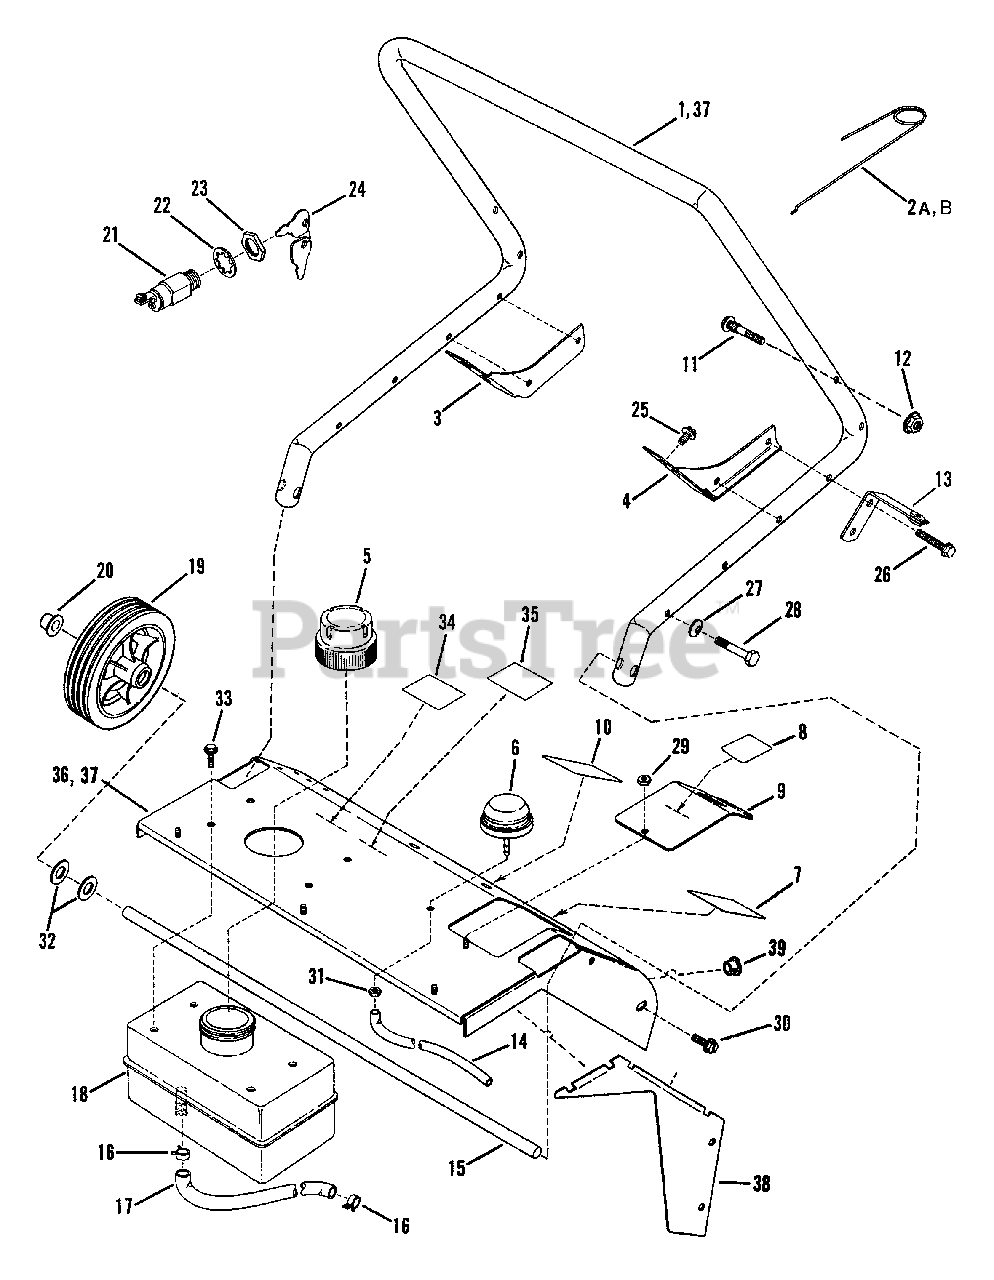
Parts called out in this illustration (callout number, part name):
1	HANDLE, Lower
2A	CONTROL, Choke (Briggs)
2B	CONTROL, Choke (Tecumseh)
3	BRACE, Handle (Right Hand)
4	BRACE, Handle (Left Hand)
5	CAP, Fuel Tank
6	PRIMER, Fuel (Tecumseh)
7	DECAL, Choke
8	DECAL, Spark Plug Access
9	COVER, Access Hole
10	DECAL, Controls
11	BOLT, 1/4-20 x 1-3/8" Square Neck Carriage, Grade 5
12	NUT, 1/4-20 Hex Flange Lock
13	ASSEMBLY, Bracket & Bushing
14	HOSE, Primer
15	AXLE
16	CLAMP, Fuel Line
17	LINE, Fuel
18	TANK, Fuel
20	NUT, 3/8" Push
21	SWITCH, Ignition
22	WASHER, 5/8" Internal Tooth Lock
23	NUT, 5/8-32 Hex (Special)
24	KEY, Ignition
25	SCREW, #10-32 x 1/4" Hex Washer Face Self-Tap
26	SCREW, 1/4-20 x 3/8" Hex Washer Face Self-Tap
27	WASHER, 1/4" Curved
28	BOLT, 114-20 x 1-1/4" Hex Head, Grade 5
29	NUT, #10-24 Hex Flange Lock
30	SCREW, Drill, #10-24 x 1/2" Hex Washer Face
31	NUT, 1/4-20 Hex Center Lock, Grade B or 5
32	WASHER, 3/8 SAE
33	SCREW, 1/4-15 x 3/4" Hex Washer Face, Self-Tap (Plastic)
34	DECAL, Fuel Mix Chart (Tecumseh)
35	DECAL, Warning, Fuel Mix (Tecumseh)
36	WELDMENT, Handle/Panel
37	ASSEMBLY, Lower Handle/Panel
38	BAFFLE, L.H.
39	PLUG, 1/2" Panel
